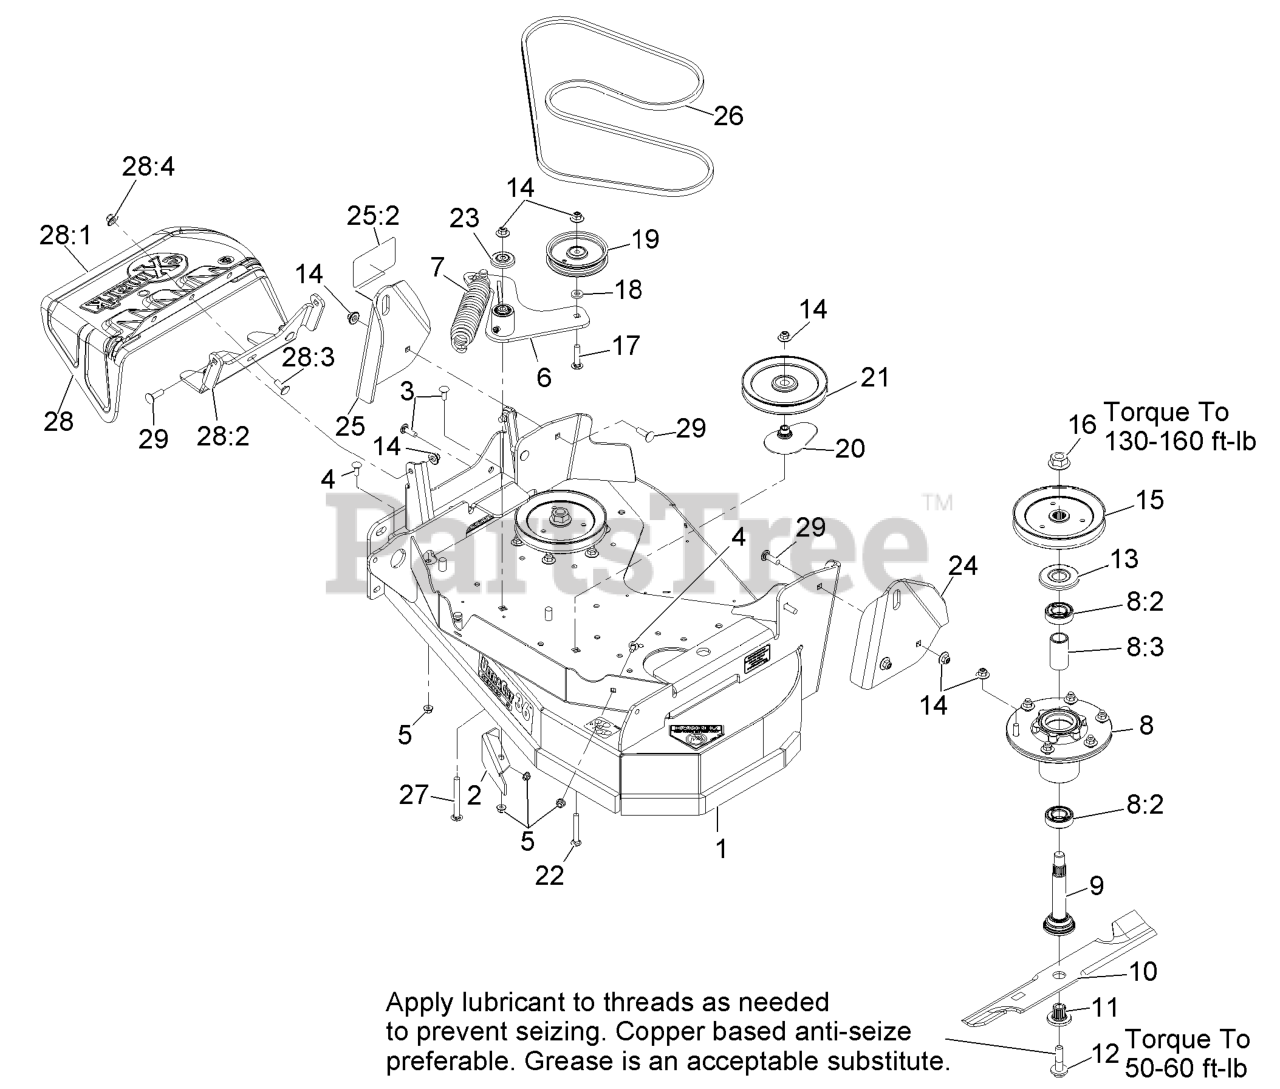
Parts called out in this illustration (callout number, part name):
1	DECK ASM - 36
2	BAFFLE-DOGLEG
3	SCREW-CARR
4	SCREW-CARR
5	NUT-HF, NI
6	IDLER ARM ASM -
8	ASM-CUTTER HSG WITH BEARINGS
8:2	BEARING-BALL
8:3	SPACER-BEARING
9	ASM-SPINDLE AND SEAL
11	BUSHING,SPLINED
12	SCREW,SEMS 1/2-20 X 2.19
13	GUARD,BEARING TOP .989
14	Nut-Nyloc 3/8-16 Flg
15	SHEAVE,BLADE DRIVE 6.50
16	NUT-FLANGE
17	SCREW-CARR
19	PULLEY-IDLER
20	SPACER-PULLEY
21	PULLEY-IDLER
22	SCREW-CARR
23	GUARD-TOP
24	PUSH-TOWER,LH 36
25	PUSH TOWER-RH 36, W/DECAL
25:2	DECAL-WARNING, DISCHARGE
26	BELT-V
27	BOLT-SHOULDER, CARRIAGE 3/8-16 X 3 1/2
28	CHUTE - DISCHARGE ASM
28:1	CHUTE,DISCHARGE
28:2	BRACKET-CHUTE, DISCHARGE
28:3	SCREW-CARR
28:4	Nut-Nyloc 3/8-16 Flg
29	Bolt-Carriage 3/8-16 X 1 1/4
